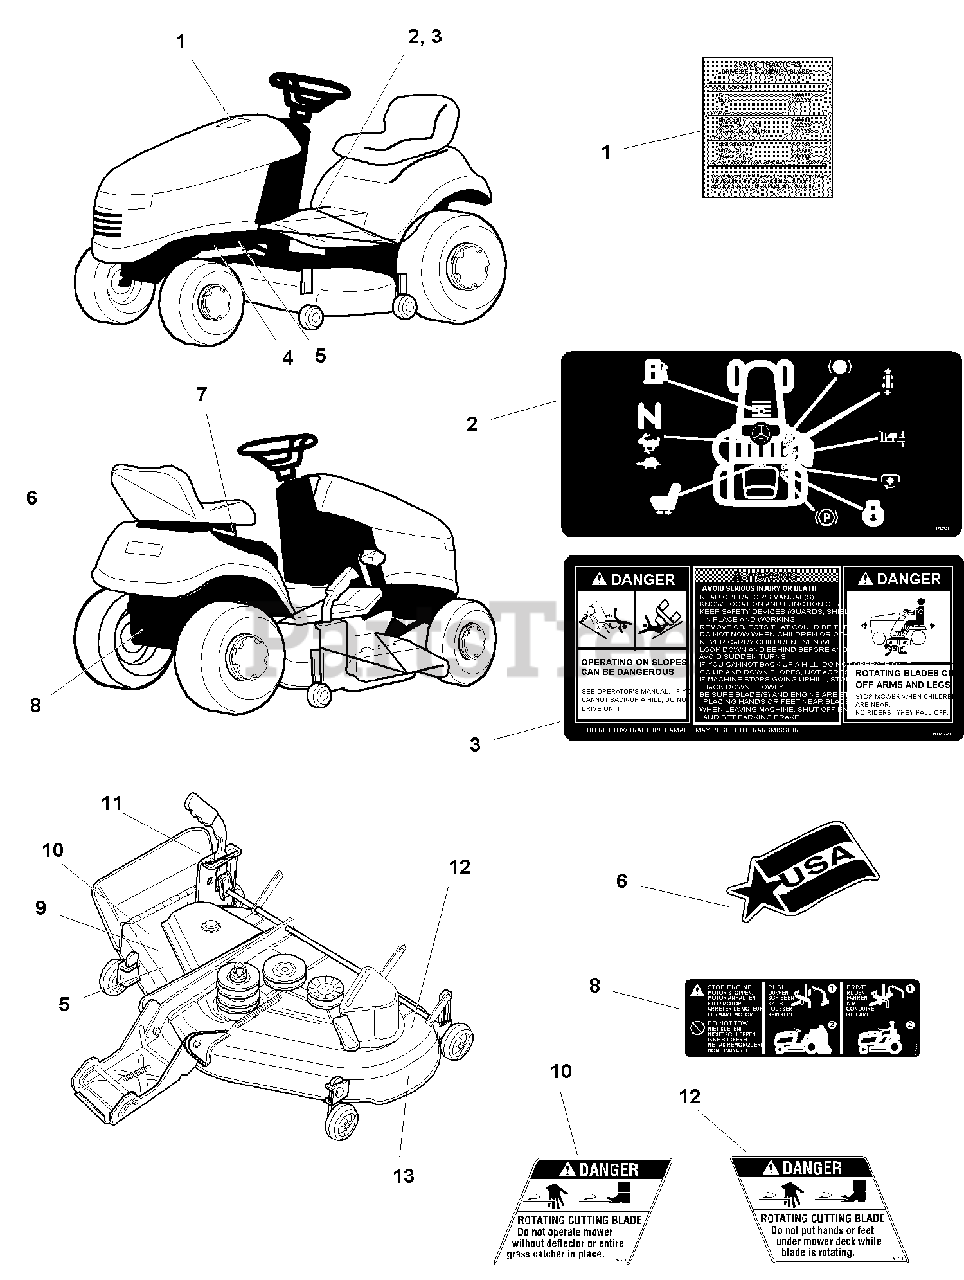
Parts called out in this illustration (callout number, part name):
1	DECAL, Belts & Mower Blades
2	DECAL, Operating Instructions
3	DECAL, Safety Instructions
3	DECAL, Safety Instructions (Export)
4	DECAL, Patent
5	DECAL, OPEI (Not Serviced)
5	DECAL, Serial Number (Not Serviced)
5	DECAL, CE & Serial Number Export (Not Serviced)
6	DECAL, USA Logo
7	DECAL, PTO Control Symbols
8	DECAL, Transmission Release Valve, Hydros only
10	DECAL, DANGER
11	DECAL, Height Of Cut
11	DECAL, Height of Cut
12	DECAL, DANGER
13	DECAL, Free Floating Mower
